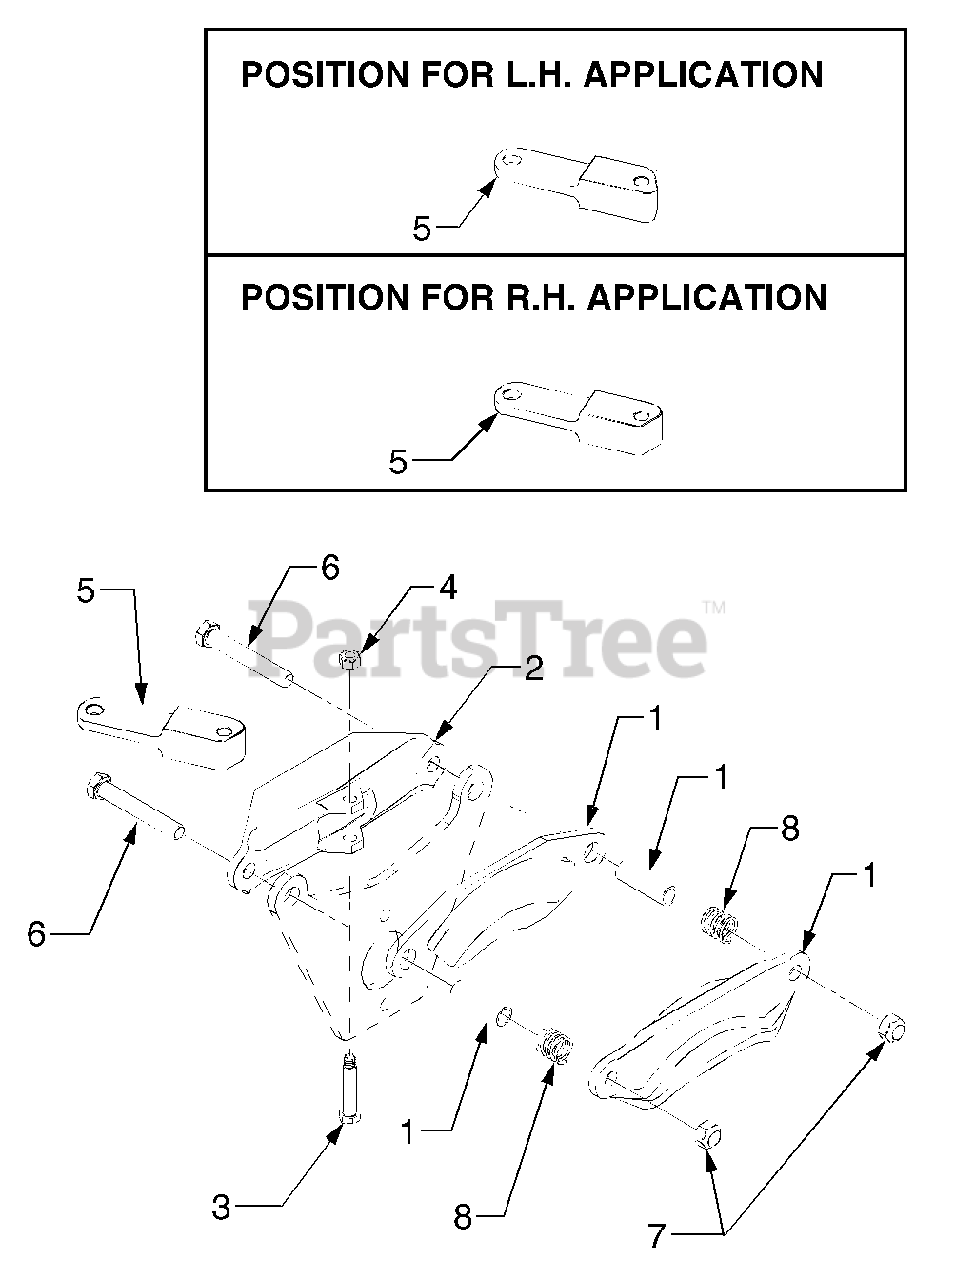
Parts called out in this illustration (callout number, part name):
1	KIT-BRAKE PUCK SVC
2	Bracket, Brake Actuator
3	Screw, Shoulder
4	Nut, Hex Top Lock, 1/4-20
5	Arm, Brake Actuator
6	Screw, Hex Cap, 3/8-24 x 2.5 GR5 4
7	Nut, Hex Lock, 3/8-24
8	Spring, Compression
